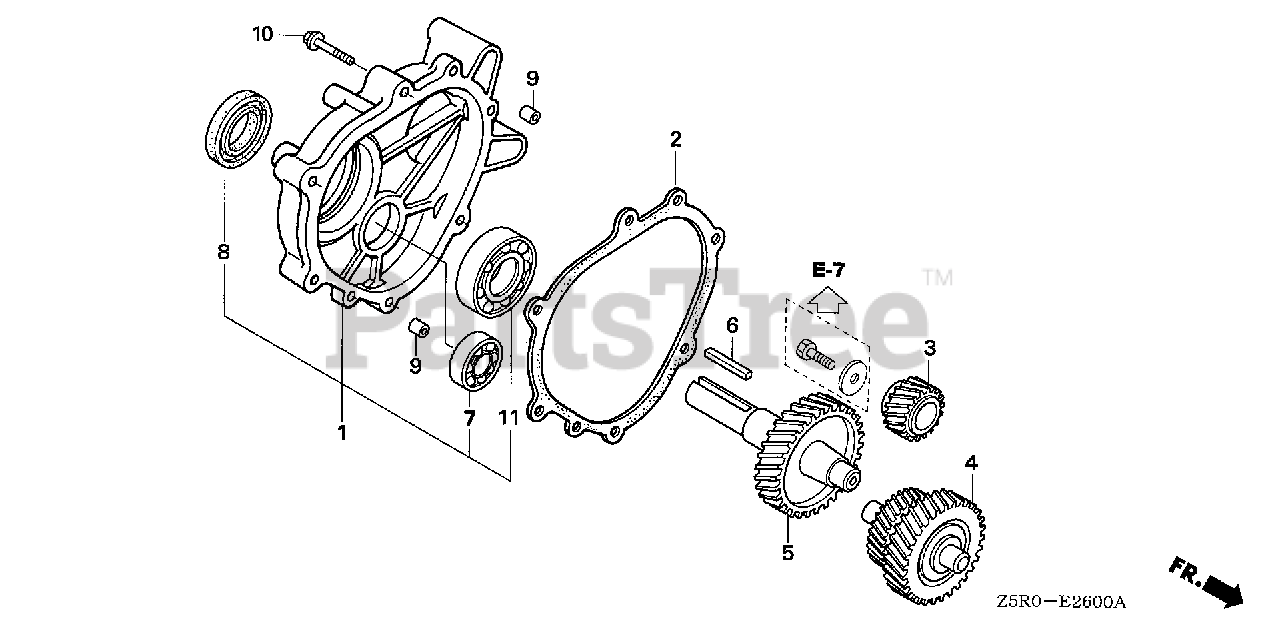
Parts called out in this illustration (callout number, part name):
1	COVER ASSY., GEAR CASE
2	GASKET, CHAIN CASE COVER
3	GEAR, PRIMARY DRIVE (22T)
4	COUNTERSHAFT (21T/27T)
5	SHAFT, P.T.O. (33T)
6	KEY (7X7X33) (OVER SIZE) (YELLOW)
7	BEARING, RADIAL BALL (6202) (NTN)
8	OIL SEAL (30X46X8)
9	PIN, DOWEL (8X14)
10	BOLT, FLANGE (8X40)
11	BEARING, RADIAL BALL (6206)
